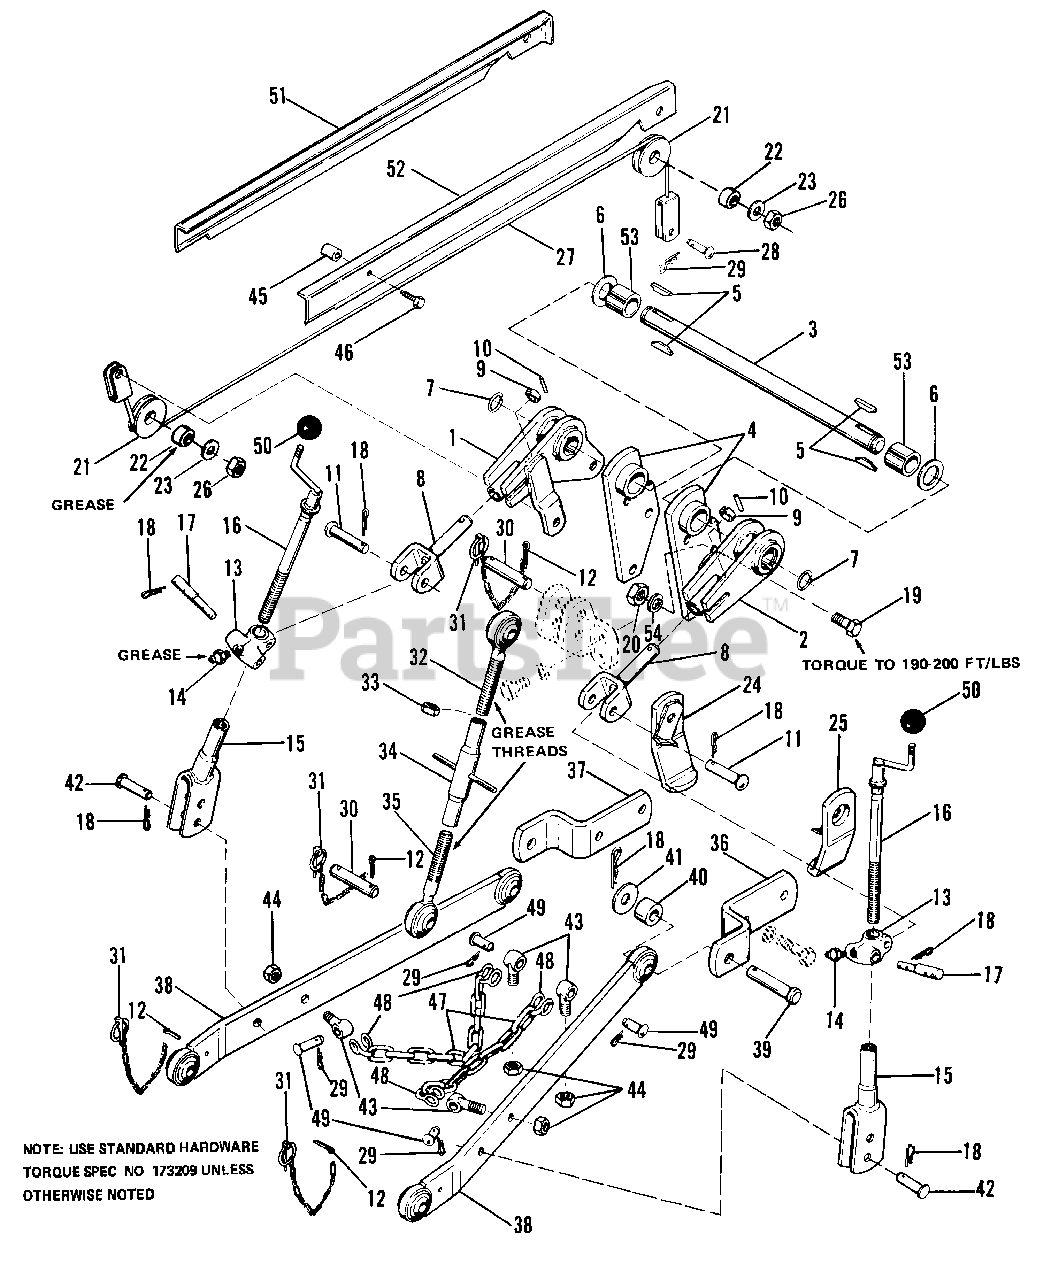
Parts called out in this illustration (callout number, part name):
1	ARM ASSY, Lift, L.H.
2	ARM ASSY, Lift, R.H.
3	SHAFT, Rocker
4	SUPPORT ASSY
7	RING, Retaining
8	CLEVIS ASSY
10	PIN, Spring, 1/4 x 1-1/4
12	PIN, Cotter, 1/4 x 1-1/2
14	FITTING, Lube, 1/4
15	CLEVIS ASSY
16	LINK ASSY
18	CLIP, Spring
19	CAPSCREW, Hex, 5/8-11 x 2, Gr. 8
20	NUT, Heavy, 5/8-11
21	PULLEY, Cable
23	WASHER, 7/16
24	BAR ASSY, Rub, L.H.
25	BAR ASSY, Rub, R.H.
26	NUT, Hex, Lock, Jam, 1/2-13
29	CLIP, Spring
31	RING, Retaining
32	STUD ASSY, R.H. Thread
33	NUT, Hex, Full, 3/4-10
34	LINK ASSY, Upper
35	STUD ASSY, L.H. Thread
36	STRAP, Pull Link, R.H.
37	STRAP, Pull Link, L.H.
38	LINK ASSY, Pull
43	BOLT, Eye
44	NUT, Hex, Lock, 1/2-20
46	SCREW, Thr. Form, 1/4 x 1-1/4
49	PIN
51	GUARD, Wire, L.H.
52	GUARD, Wire, R.H.
54	LOCKWASHER, 5/8
